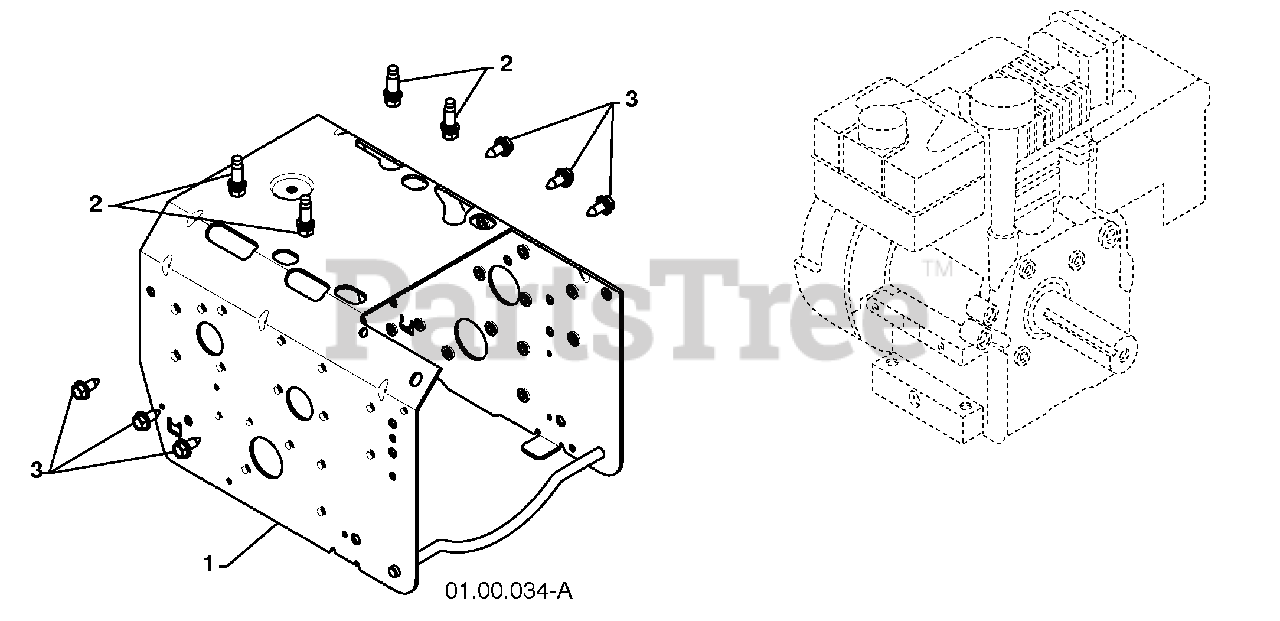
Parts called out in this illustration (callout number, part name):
1	FRAME
2	BOLT 3/8-16
3	SCREW 5/16-18 X .750
